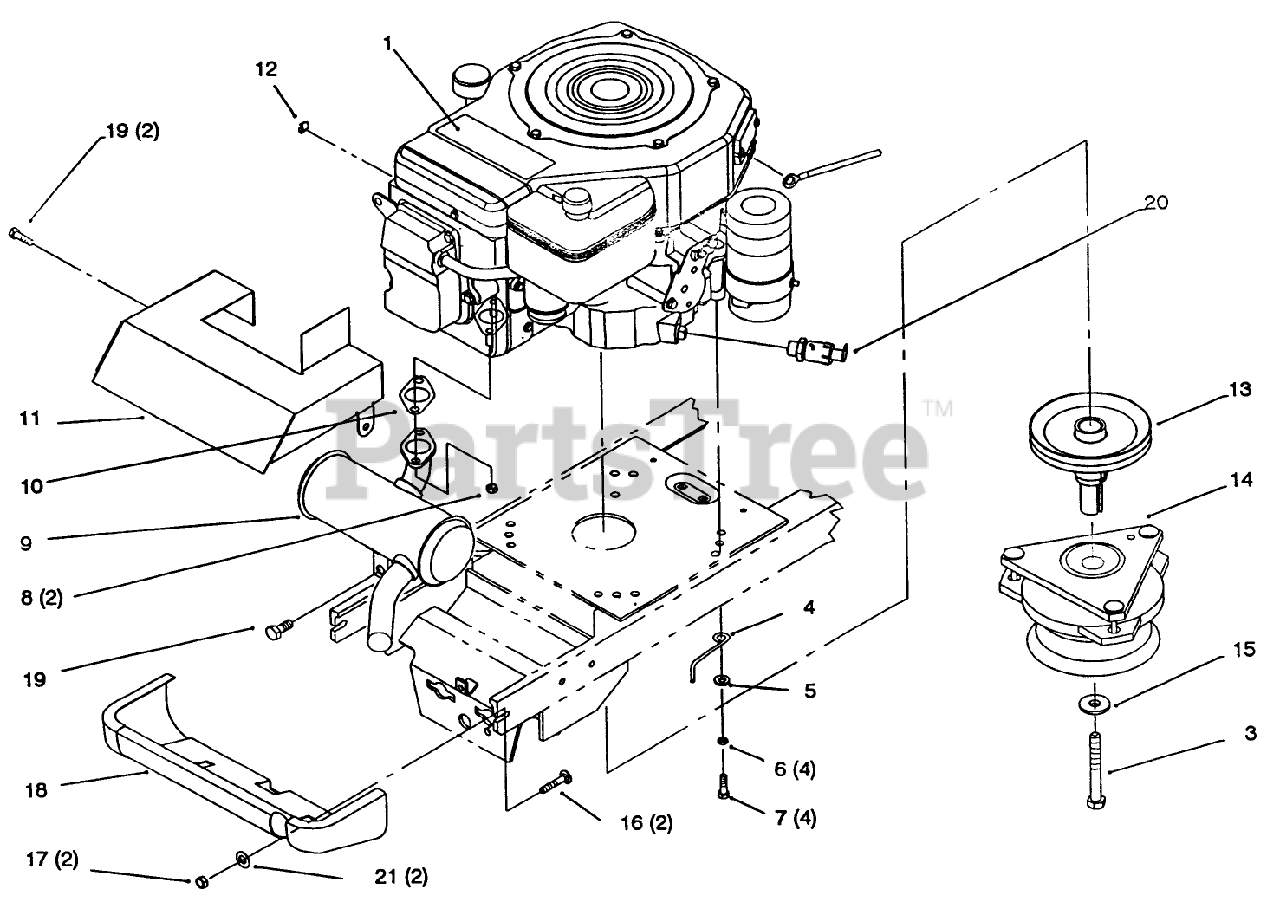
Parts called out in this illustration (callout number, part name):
1	DECAL - ENGINE
3	HHCS-M10X1.5X110 ESL
4	GUIDE-BELT
5	WASHER-PLAIN
6	WASHER-LOCK
10	KOHLER 12-041-03
11	SHIELD-MUFFLER
12	CLIP-RETAINER, WIRE
13	PULLEY-ENGINE
13	PULLEY- ENGINE GEAR
14	CLUTCH - ELEC PTO
15	WASHER
16	SCREW-CARR
17	NUT-LOCK, NI
19	SCREW
20	VALVE-DRAIN, OIL
21	WASHER-FLAT
